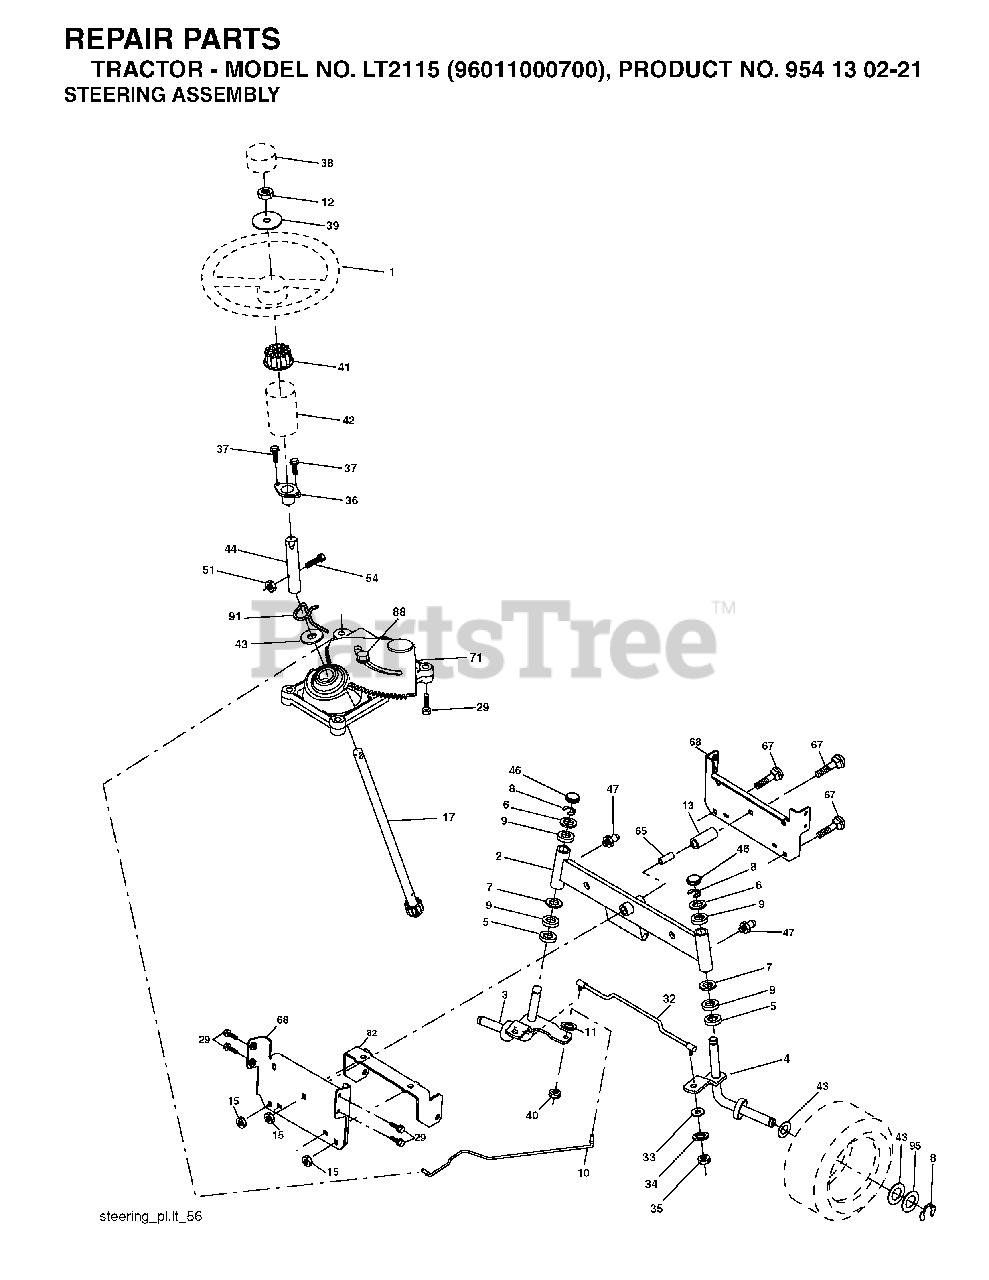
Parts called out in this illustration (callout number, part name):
2	AXLE ASM.
3	SPINDLE.ASM.LH.15"TIRES
4	SPINDLE.ASM.RH.15"TIRES
8	RING CLIP
9	BRNG T
10	DRAGLINK.15".TIRES.2001
11	WASHER, LOCK 3/8
12	NUT.HEX.1/2-20
13	TUBE, PIVOT AXLE
15	NUT
17	SHAFT ASM, STEERING
29	SCREW, 3/8-16X3/4
33	WASHER M
34	LOCKWASHER
35	NUT, CROWNLOCK
36	BUSHING, STEERING
38	INSERT.CAP.STRG.WH.BLACK
39	WASHER 9/16"ID, 2 3/8"OD
40	NUT CROWNLOCK 3/8-24
41	ADAPTER, WHEEL STNG..
42	BOOT.STEERING.SHAFT.BLACK
44	EXT, STEERING SHAFT
46	CAP.SPINDLE
47	FITTING.GREASE.TAPERED
51	CROWN LOCKNUT
65	SPACER BRACE AXLE
67	BOLT CARRIAGE
68	BRACE.AXLE.15"TIRES
71	STEERING ASM
82	BRACKET
88	BOLT, SHOULDER 7/16-20
91	CLIP.STEERING
95	WASHER.HARDENED
